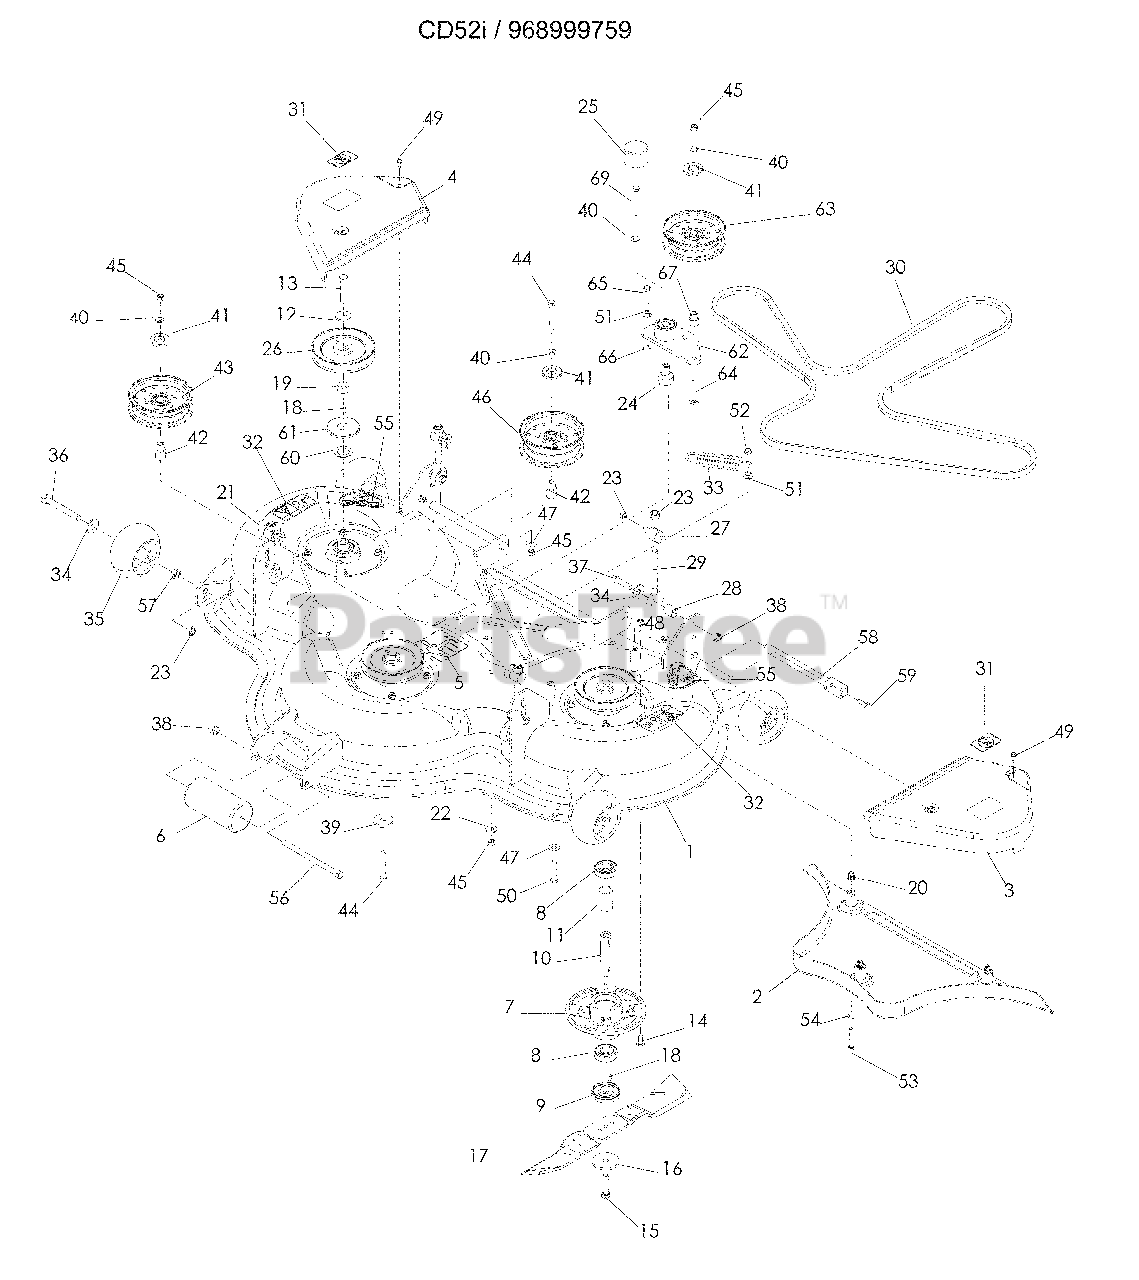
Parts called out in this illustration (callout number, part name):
1	DECK w/ DECALS
2	MULCH PLUG, 132
3	BELT SHIELD, LEFT
4	BELT SHIELD, RIGHT
5	DECAL, BELT ROUTING
6	ROLLER
7	BEARING HOUSING
9	BUSHING, BLADE
13	HCS M12 x 1.75 x 60, GR8.8
14	RHSNB 5/16-18 x 1
15	HCS M12 x 1.75 x 50, GR8.8
17	BLADE, C132
19	KEY RETAINER
20	BLIND RIVET NUT
22	SUPPORT WASHER
23	NUT ½ NYLOC
24	PIVOT, BEARING
25	CAP, VINYL
26	PULLEY, 52
30	BELT, DECK
31	DECAL, NO STEP
32	DECAL, BELT DRIVE
35	WHEEL, GAUGE
36	HCS ½-13 x 4
37	HCS 7/16-14 x 1¾
38	NUT 7/16-14 CTRLK, GR A
39	HEAVY WASHER
40	WASHER 3/8 SPECIAL
41	SHIELD, DUST
42	IDLER BUSHING
43	IDLER PULLEY
44	HCS 3/8-16 x 2¾
45	NUT 3/8 -16 NYLOC
46	IDLER PULLEY
47	WASHER 3/8
48	NUT 5/16-18 NYLOC
49	SCREW ¼-20 x 5/8 SLF TAP
50	HCS 3/8-16 x 2
51	NUT 3/8-16 WHIZLK
52	NUT 3/8-16 JAM, NYLOC
53	HCS M8 x 1.25 x 50, GR8.8
54	WASHER 5/16 SAE
55	DECAL, CPSC
56	HCS 7/16-14 x 7
59	HCS 5/16-18 x 1
60	WASHER 1.06
61	DUST CAP, BOTTOM
62	ARM w/ BEARINGS, IDLER
63	IDLER PULLEY
64	BOLT, 3/8-16 x 2½
65	HCS 3/8-16 x 1½ GR8
66	NUT 3/8-16 JAM
67	BUSHING, IDLER
68	WASHER ½ BELLEVILLE
69	HCS ½-13 x 3
